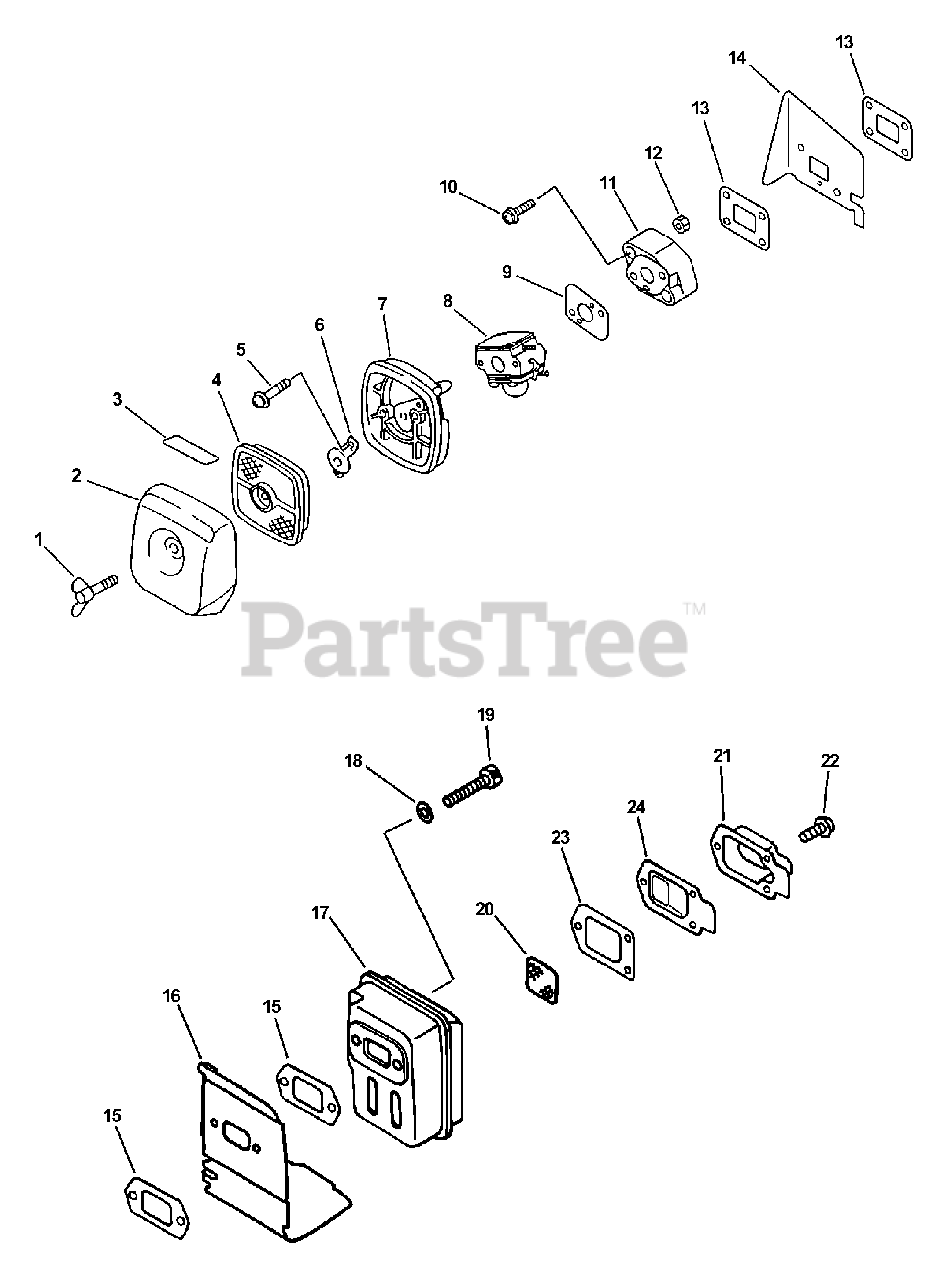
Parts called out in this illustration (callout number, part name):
1	BOLT, WING 5×20
2	COVER, AIR FILTER - GRAY
3	LABEL, CHOKE
4	FILTER, AIR - SINGLE LAYER
5	SCREW 5×65
6	PLATE, PREVENT
7	AIR FILTER CASE ASSY
8	CARBURETOR
9	GASKET, INTAKE
10	SCREW 5×22
11	INSULATOR, INTAKE
12	NUT M5
13	GASKET, INTAKE
14	HEAT SHIELD, INTAKE
15	GASKET, EXHAUST
16	COVER, MUFFLER
18	WASHER 5.5×12×0.8
19	BOLT 5×55
20	SCREEN, SPARK ARRESTER
21	GUIDE, EXHAUST
22	SCREW 4×10
23	GASKET, EXHAUST
24	GUIDE, EXHAUST
24	GUIDE, EXHAUST - INNER
